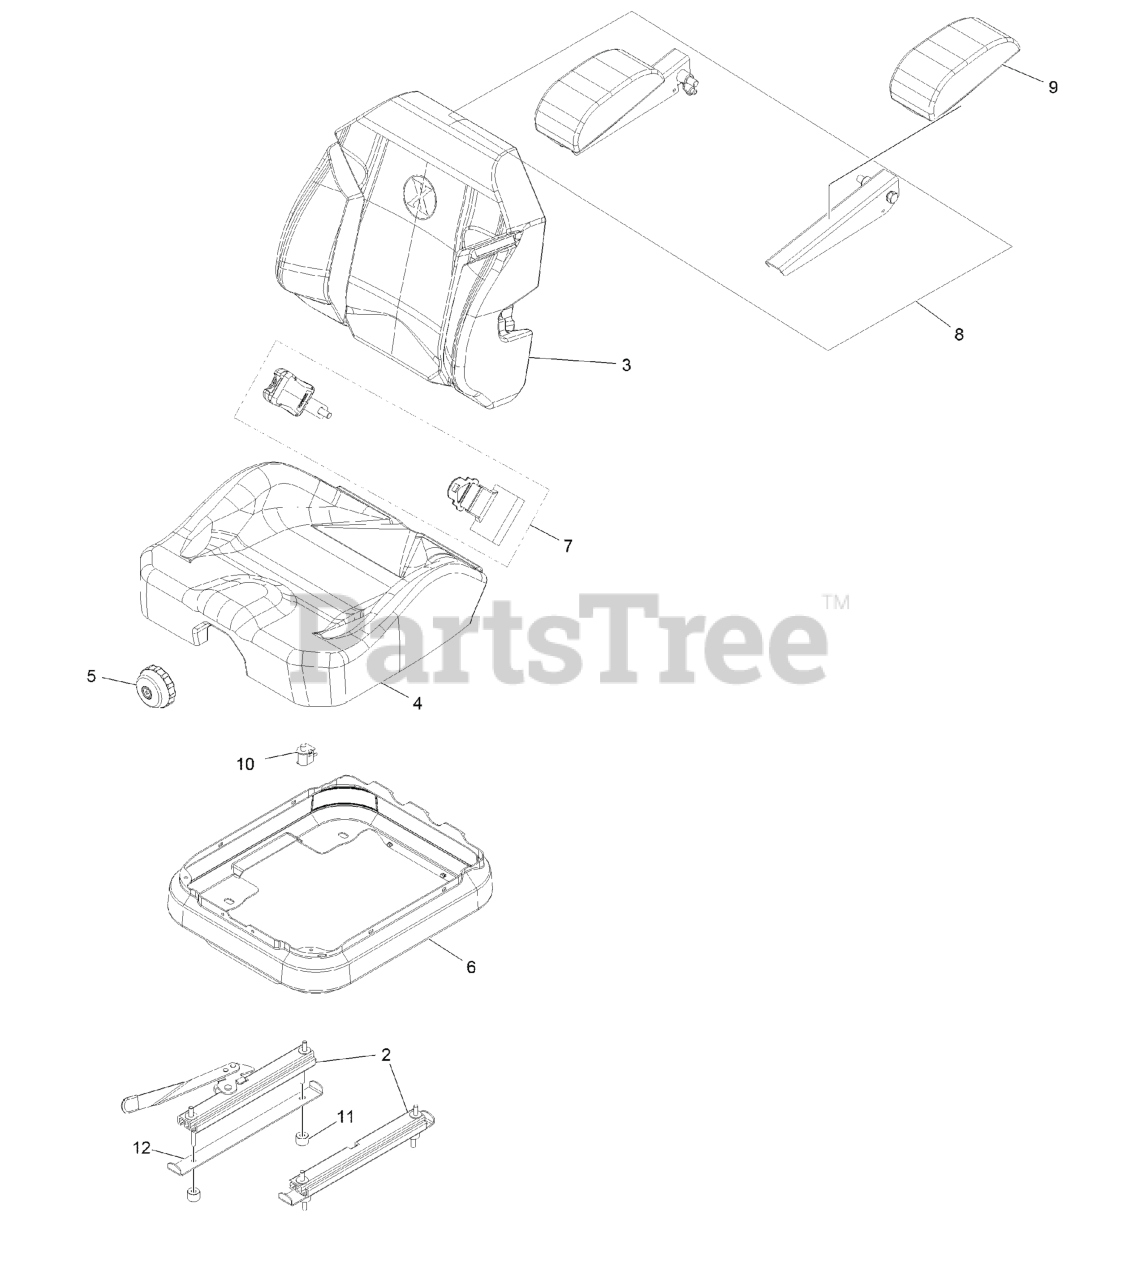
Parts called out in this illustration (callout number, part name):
2	SEAT TRACK SET
3	COVER-BACK 311463VN500
4	COVER-CUSHION 311464VN500
5	KNOB-ADJUSTER
6	COVER-SUSPENSION, BELLOWS
7	SEAT BELT SERVICE KIT
8	KIT-ARM REST SET
9	KIT-ARM REST PADS
10	SWITCH-BAIL
12	STOP, SEAT
